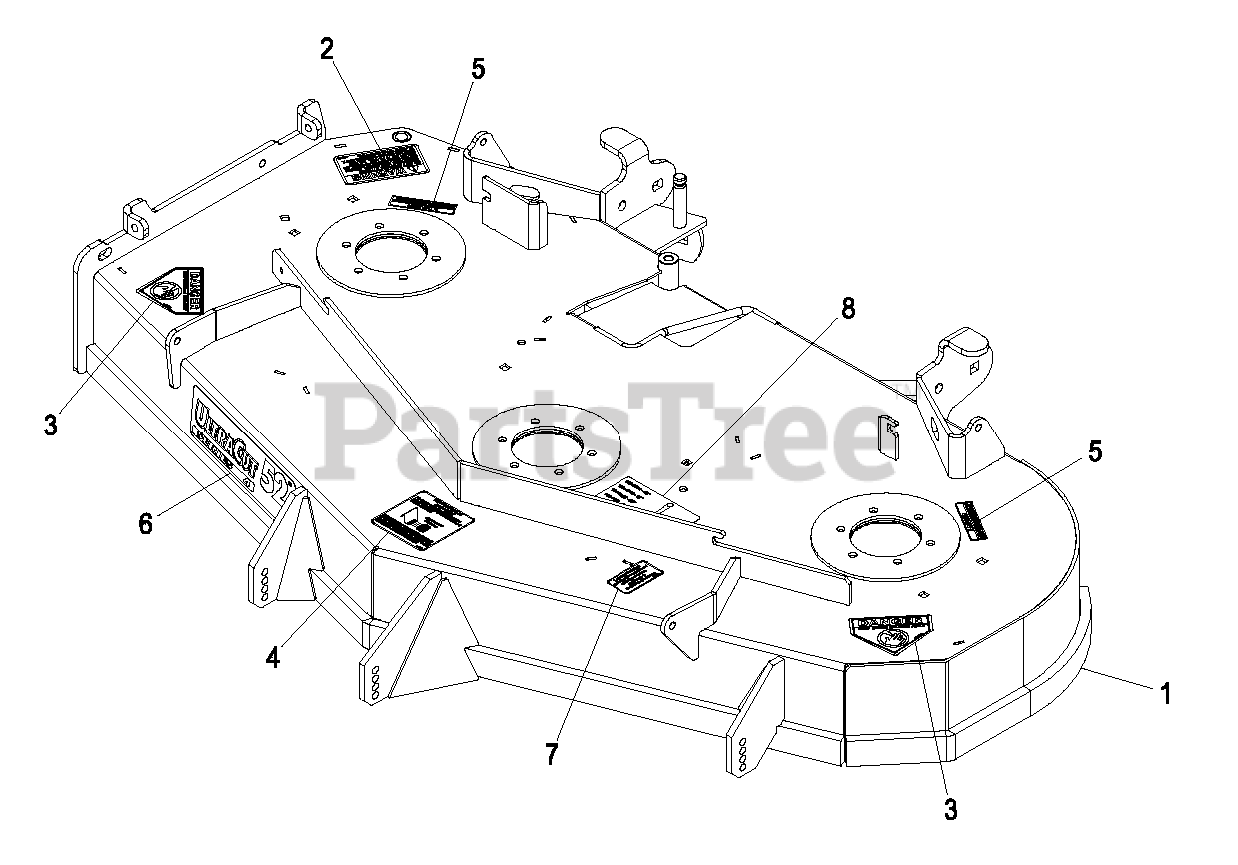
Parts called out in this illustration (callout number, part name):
2	DECAL-WARNING, DISCHARGE
3	DECAL-DANGER
4	DECAL,ANTISCALP
5	DECAL-COVER, MISSING
6	DECAL,ULTRACUT 52 SERIES
7	DECAL,BOLT TORQUE
8	DECAL,BELT ROUTING
